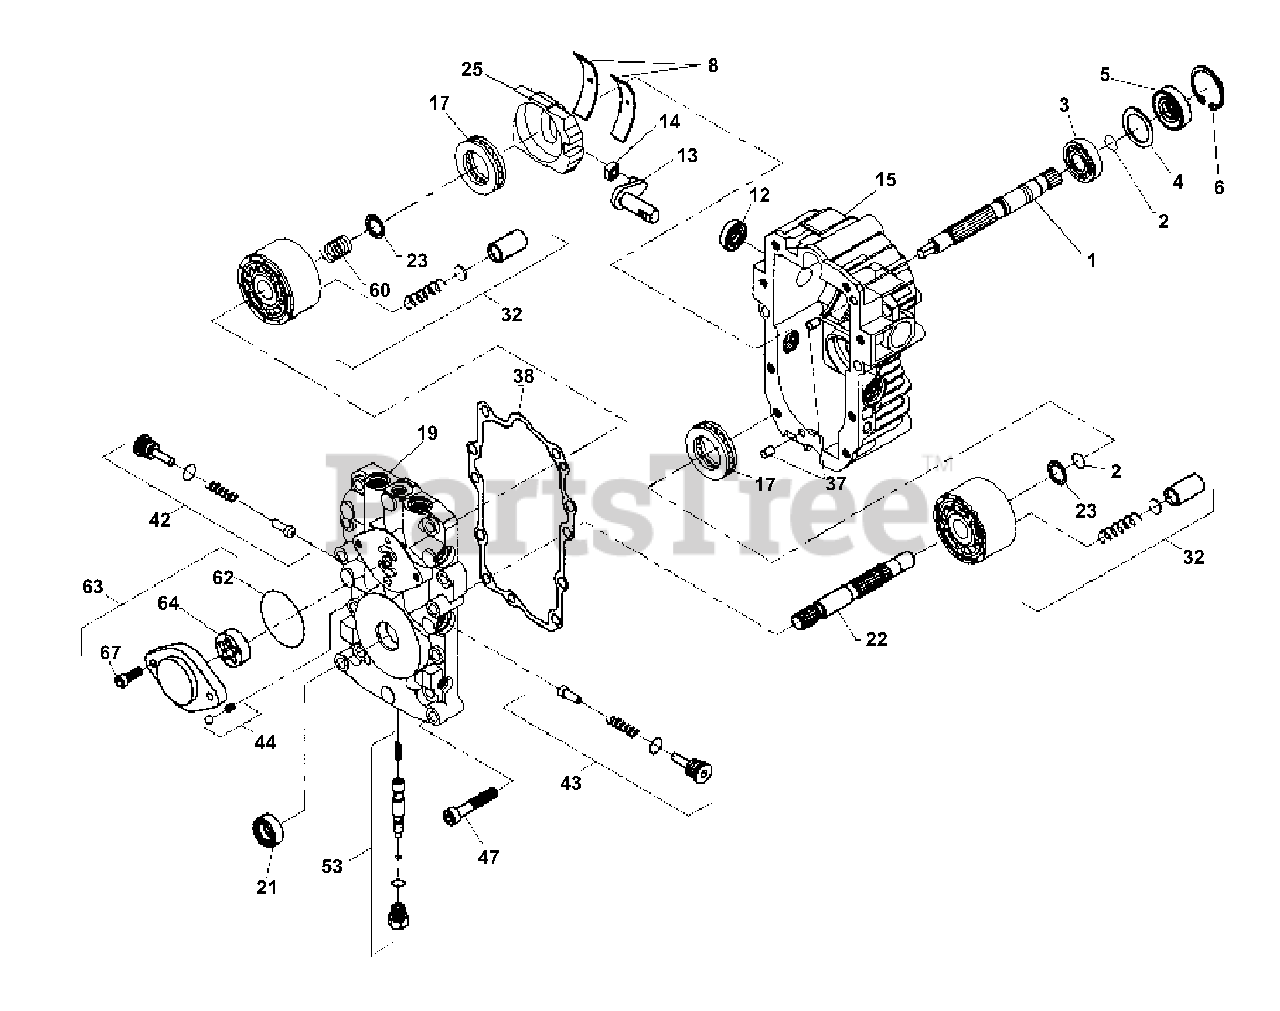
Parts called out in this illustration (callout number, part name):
1	Shaft, Pump
2	Ring, Retaining
3	Bearing, Ball
5	Seal, Lip
6	Ring, Retaining
8	Bearing, Cradle
13	Arm, Trunnion
14	Guide, Slot
15	Housing Kit, Transmission
17	Bearing, Thrust, Ball
19	Center Section Kit
22	Shaft, Motor
23	Washer, Block Thrust
25	Swashplate, Variable
32	Block Assembly
37	Pin, Stainless, Headless
38	Gasket, Center Section
42	Check Valve Kit
43	Check Valve Kit
44	Charge Relief Kit
47	Screw, Socket Head, Cap
53	Bypass Valve Kit
60	Block Spring
63	Charge Pump Kit
64	Gerotor Assembly
67	Screw, Socket Head, Cap
